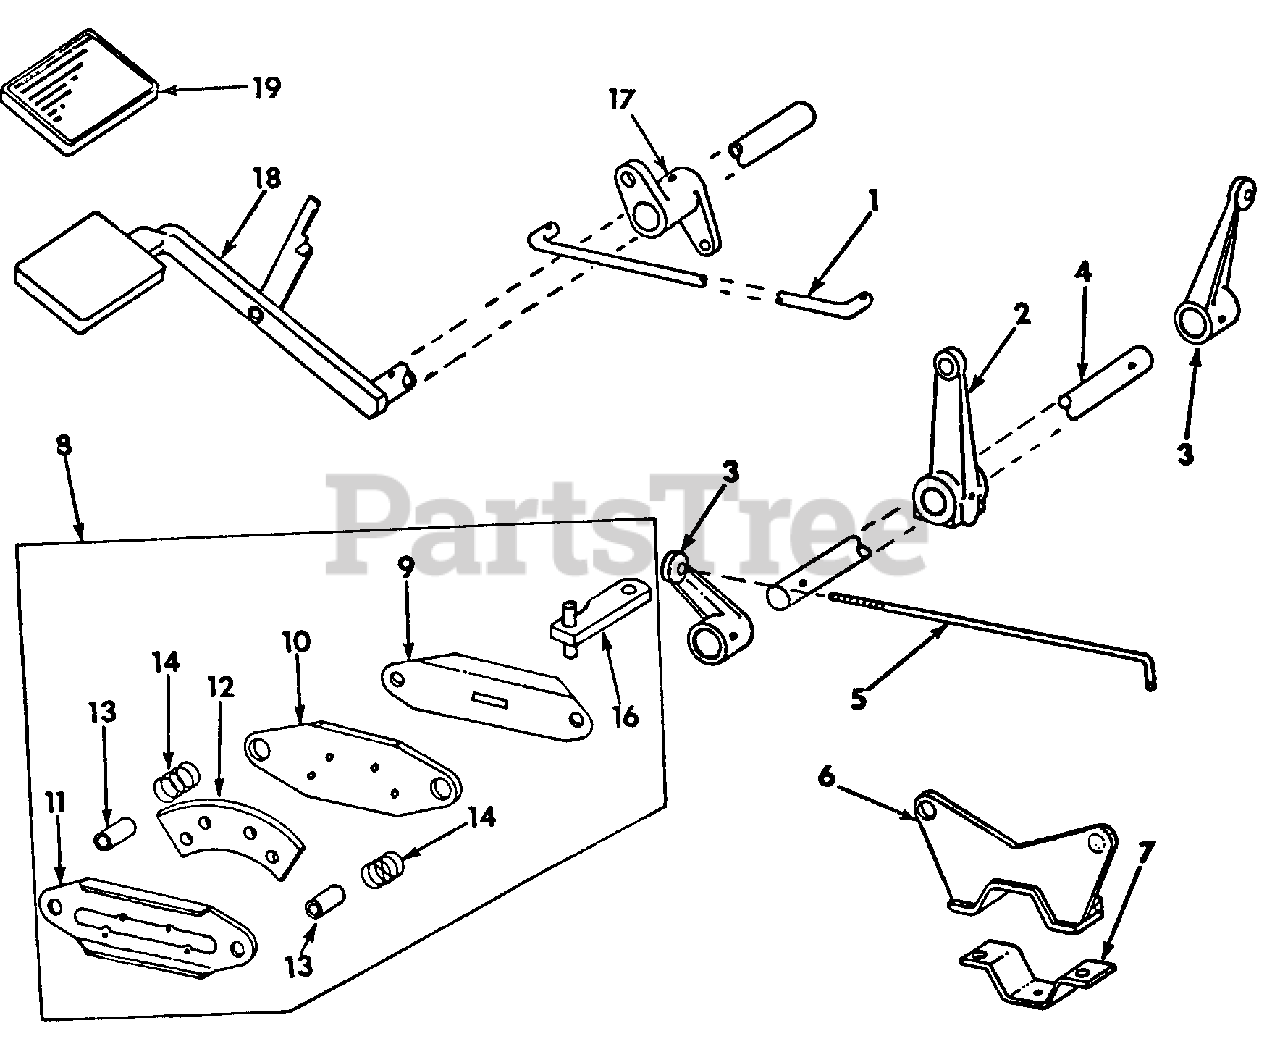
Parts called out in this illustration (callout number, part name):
2	Lever, Brake
4	Shaft, Brake Pivot
6	Bracket Assy, Caliper
7	Flange, Caliper Mounting
8	Caliper Assy, Brake
9	Plate, Actuator Cam
10	Carrier, Flat Rib
11	Carrier, Rib Plate
12	Liner, Brake
13	Bushing, Caliper
14	Spring, Compression
17	Arm, Release
18	Pedal Assy, Clutch & Brake
19	Pad, Pedal
